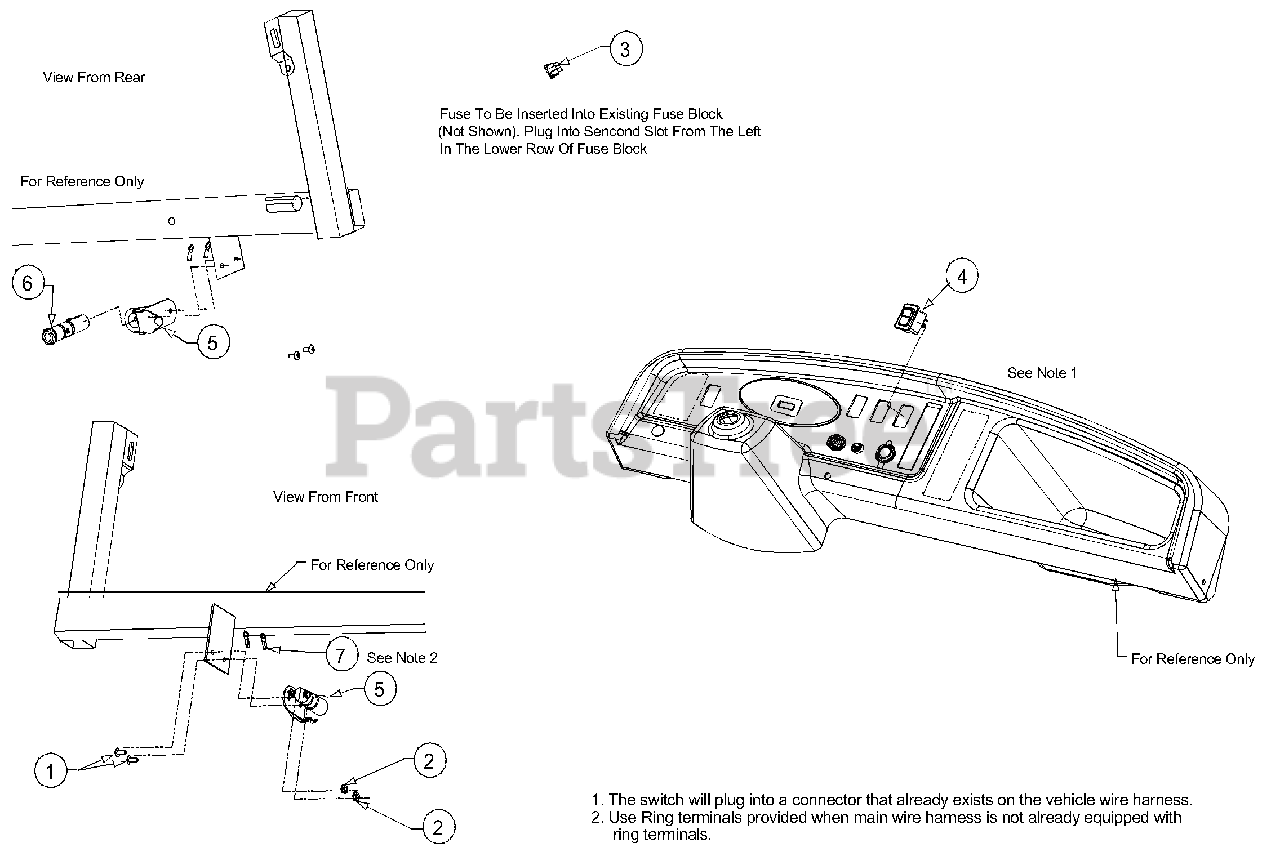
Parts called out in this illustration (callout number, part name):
1	Screw, Machine #10-24 x .50
2	Nut, Hex #10-24
3	Fuse, 15 AMP
4	Switch, Power Recepticle
5	Recepticle, Power 12V/15A
6	Recepticle, Plug
7	Terminal, #10 Ring
